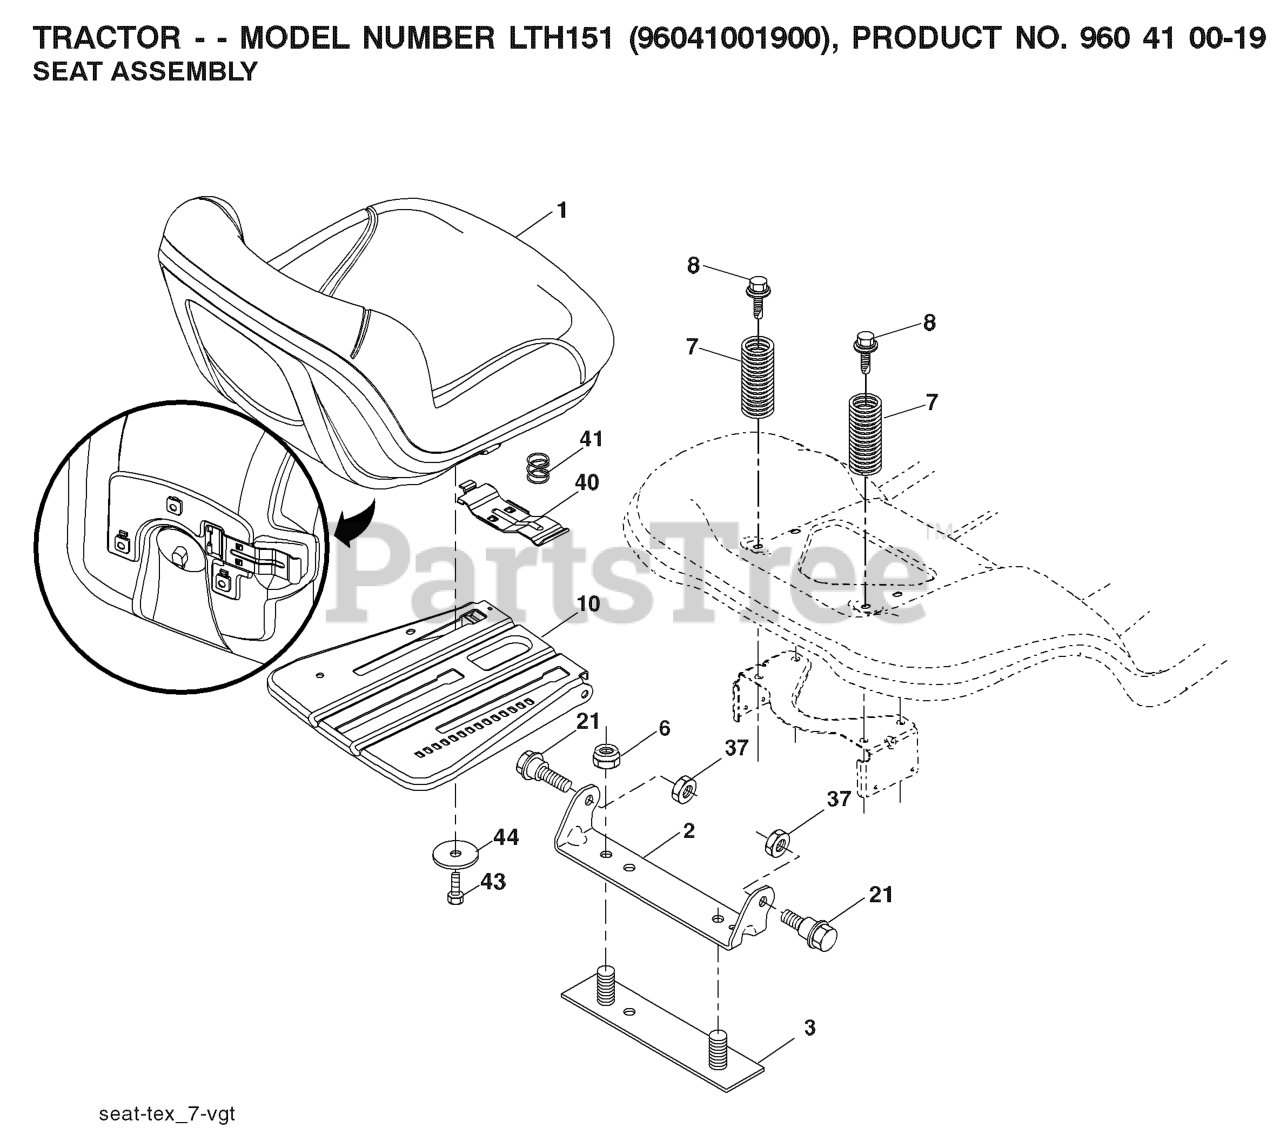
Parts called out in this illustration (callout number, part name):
1	SEAT.TH130.GRY.MILSCO.
2	BRKT.PIVOT.FENDER
3	STRAP
6	NUT
7	SPRING COMPRESSION
8	BOLT.5/16-18UNCX3/4 W/SEMS.BLK
10	PAN.ASM.SEAT.3PT
21	BOLT.SHOULDER.5/16-18
37	NUT.71038.31-18.HEX.NYLOCK
40	HANDLE.SLIDE.SEAT.TEX.BLACK
41	SPRING.LATCH.SEAT.TEX
44	WASHER 13/32 X 2-3/8 X 12GA
